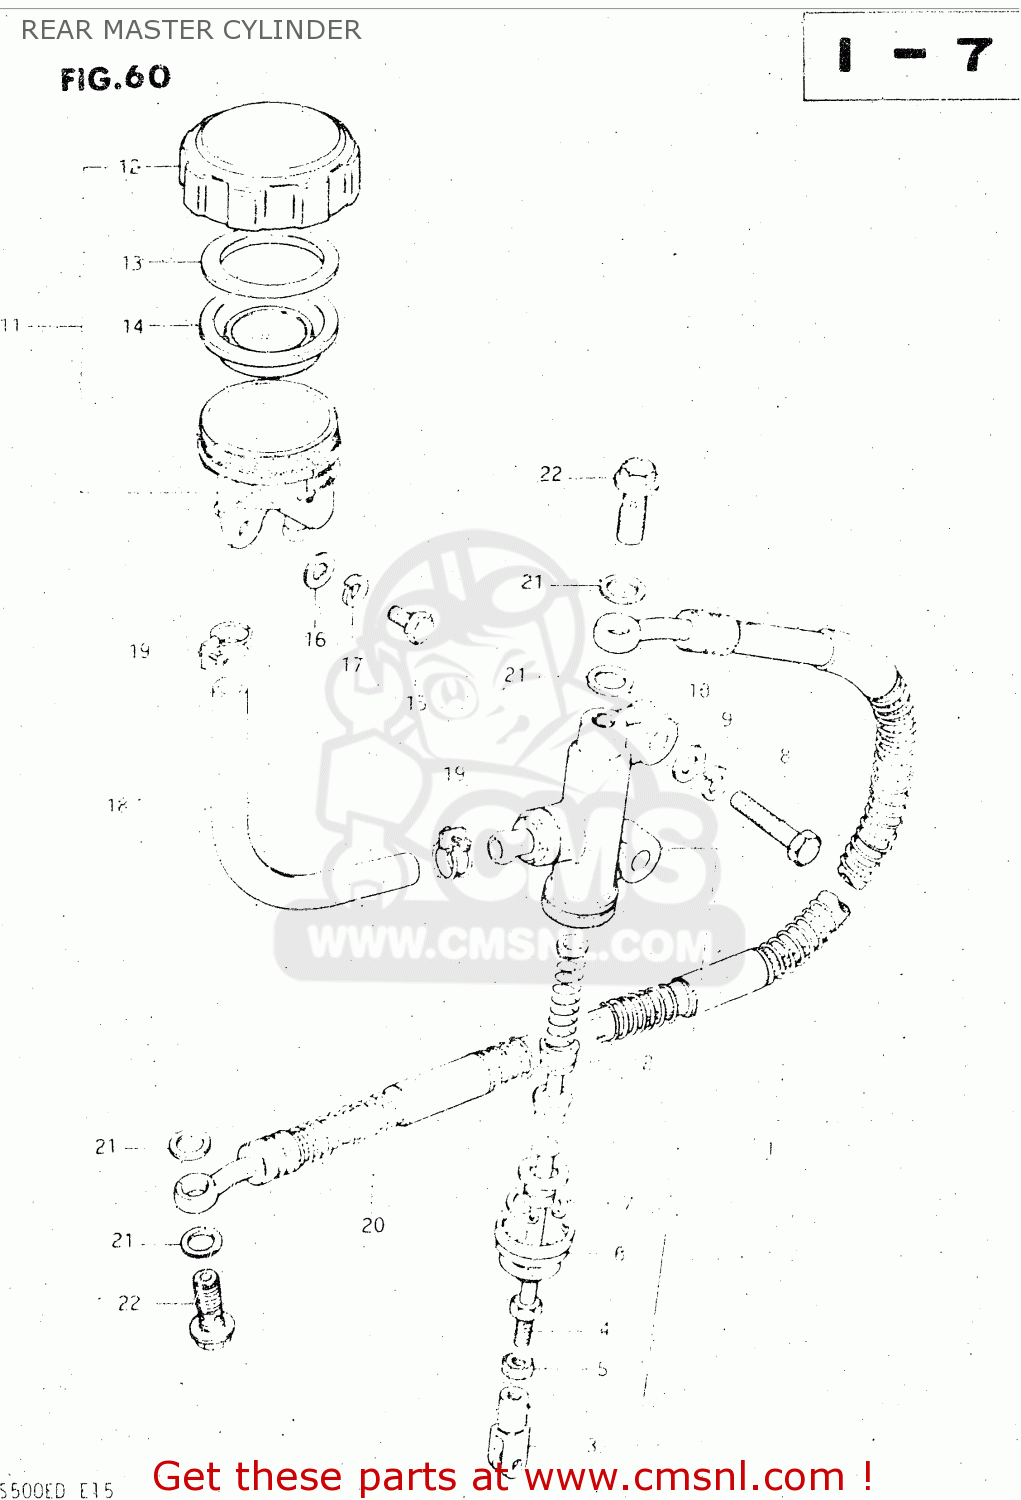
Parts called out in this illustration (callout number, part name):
1	CYLINDER ASSEMBLY,REAR MASTER
2	PISTON & CUP SET
3	YOKE
4	ROD,PUSH
5	NUT,MASTER CYLINDER
6	BOOT
7	CIRCLIP
8	BOLT (8X30)
9	LOCK WASHER
10	WASHER
11	TANK ASSEMBLY,RESERVOIR
12	CAP
13	PLATE,DIAPHRAGM
14	DIAPHRAGM
15	BOLT, UPPER
16	WASHER
17	LOCK WASHER
18	HOSE,RESERVOIR TANK
19	CLAMP
20	HOSE,REAR BRAKE
21	WASHER
22	BOLT,UNION
